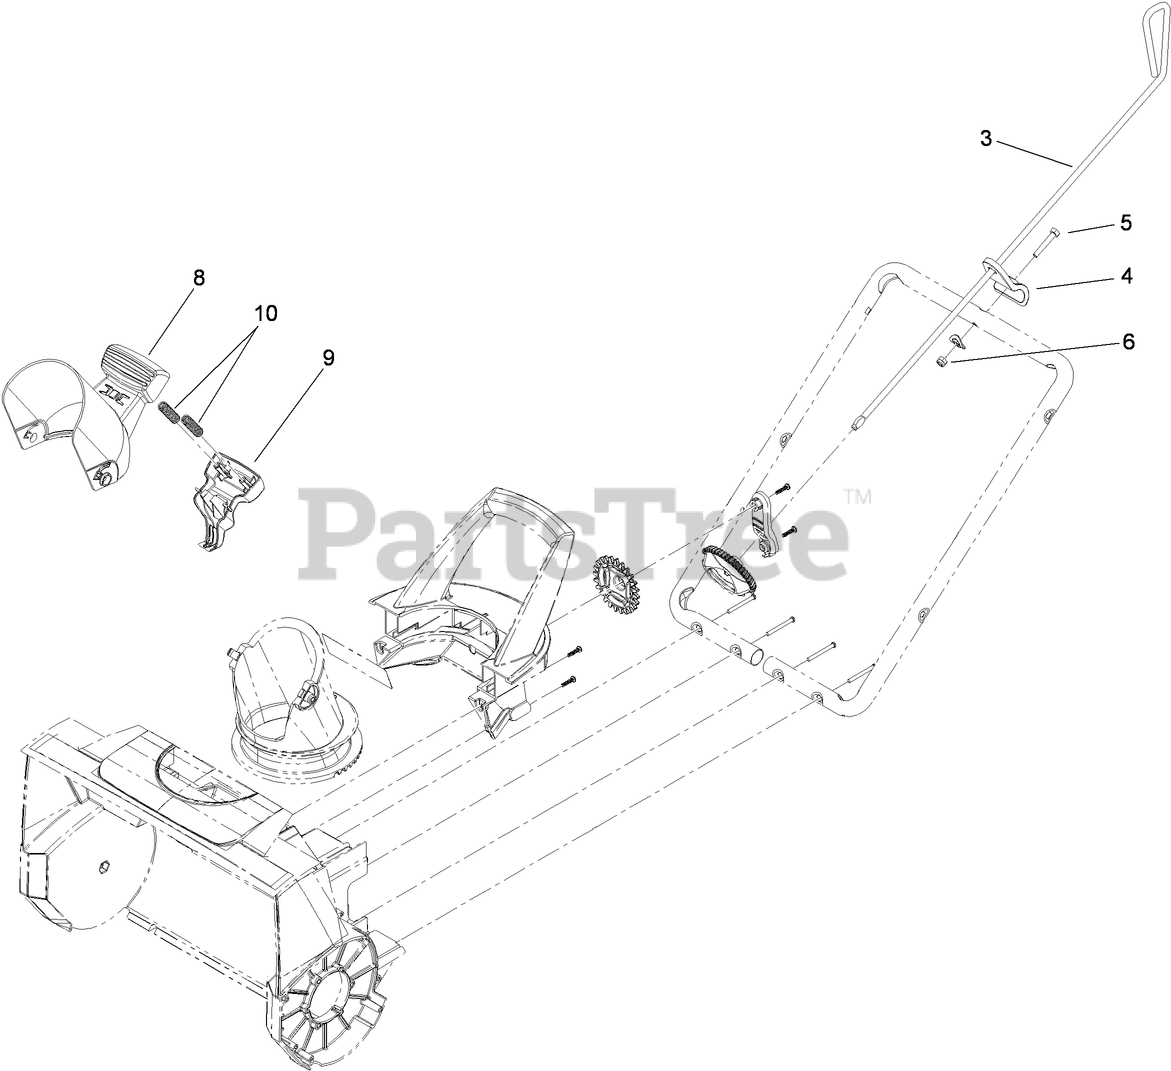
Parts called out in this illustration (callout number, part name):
3	ROD-CONTROL, CHUTE
4	GUIDE-ROD, CHUTE
5	SCREW-HH
6	NUT-LOCK, NI
8	CHUTE DEFLECTOR ASM
9	TRIGGER-DEFLECTOR
10	SPRING-COMPRESSION
